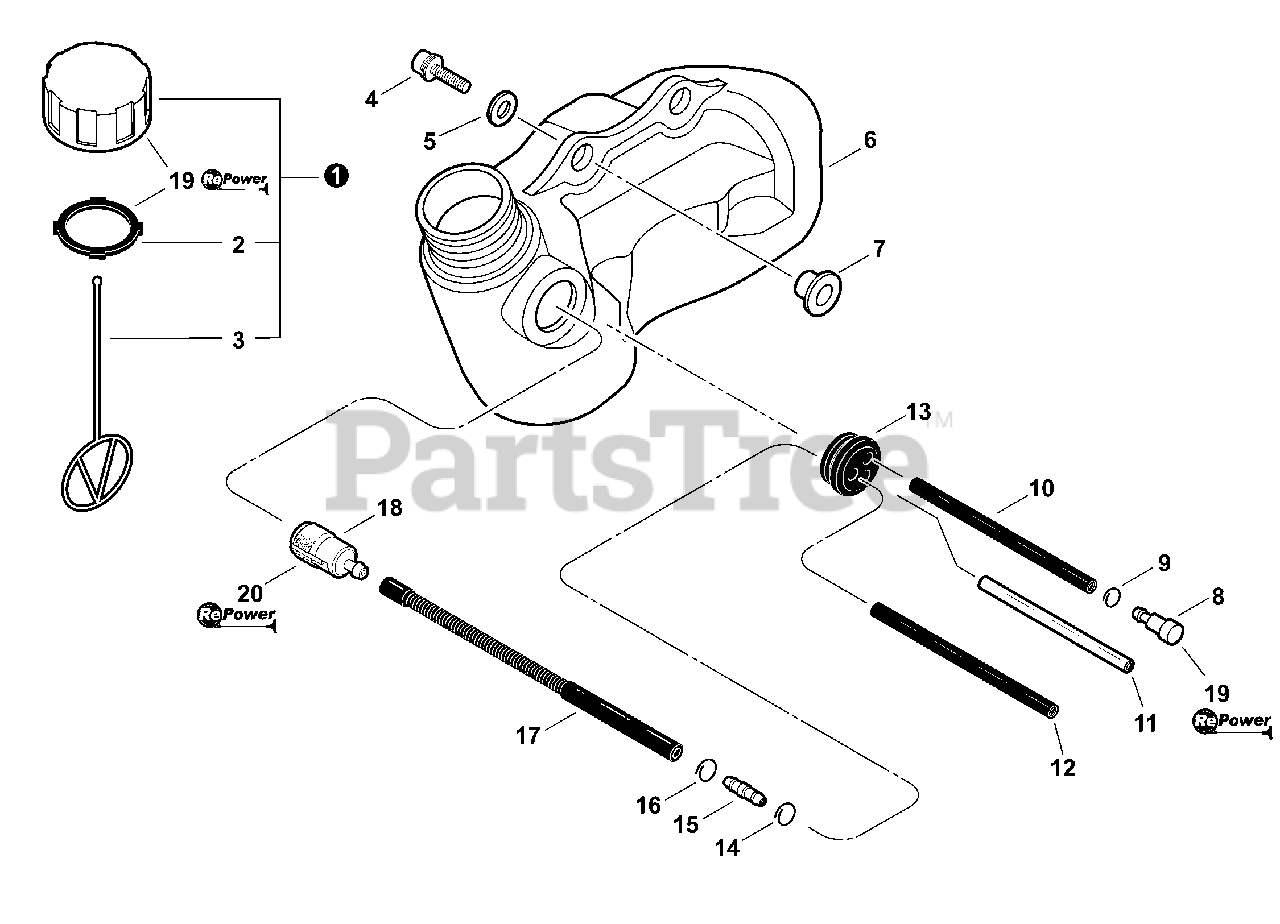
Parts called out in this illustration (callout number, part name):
1	CAP ASSY
2	GASKET, CAP
3	CONNECTOR, CAP
4	SCREW - 5×20
5	WASHER - 5
6	TANK, FUEL
8	VENT, FUEL TANK
9	CLIP - 6.6
10	PIPE - 3×6×65 -- BLACK
11	PIPE - 3×6×75 -- CLEAR
12	PIPE - 3×6×105 -- BLACK
13	GROMMET
14	CLIP - 6
15	CONNECTOR, PIPE
16	CLIP - 6.5
17	PIPE, FUEL - CORRUGATED
18	FILTER, FUEL
19	Repower CAP AND VENT KIT
20	RePower FILTER KIT
21	RePower TUNE-UP KIT
